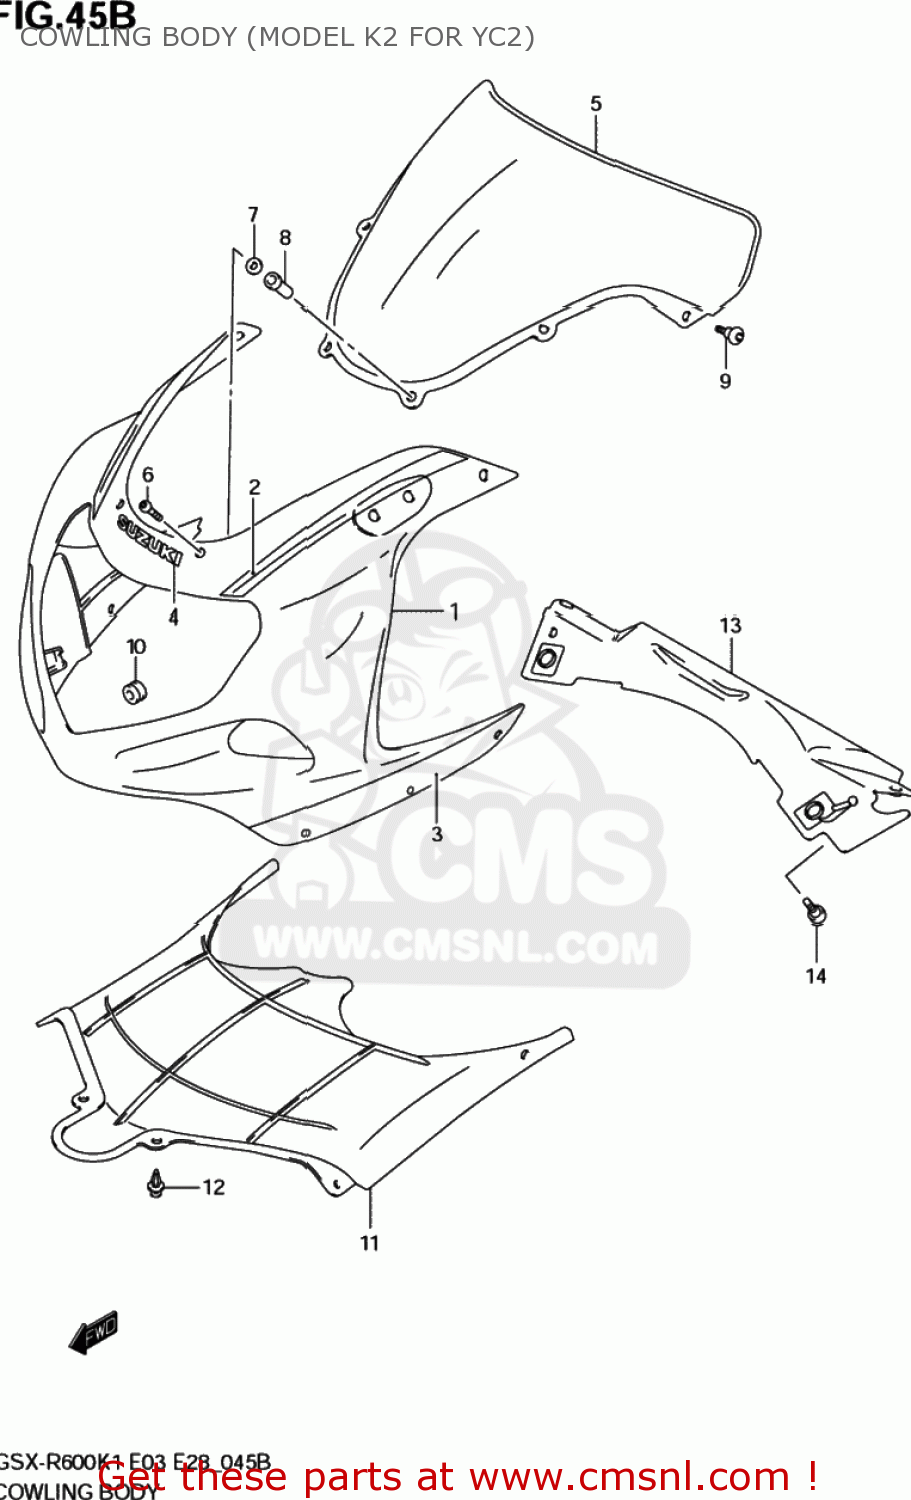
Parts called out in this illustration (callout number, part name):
1	COWLING,BODY(BLUE)
2	TAPE SET,BODY FR
3	TAPE SET,BODY SIDE
4	EMBLEM,COWLING UPR
5	WINDSCREEN
6	SCREW(5X14)
7	WASHER
8	NUT
9	SCREW(5X16)
10	CUSHION
11	COVER,BODY COWLING
12	CLIP(BLACK)
13	COVER,COWLING FR LWR
14	BOLT(5X16)
